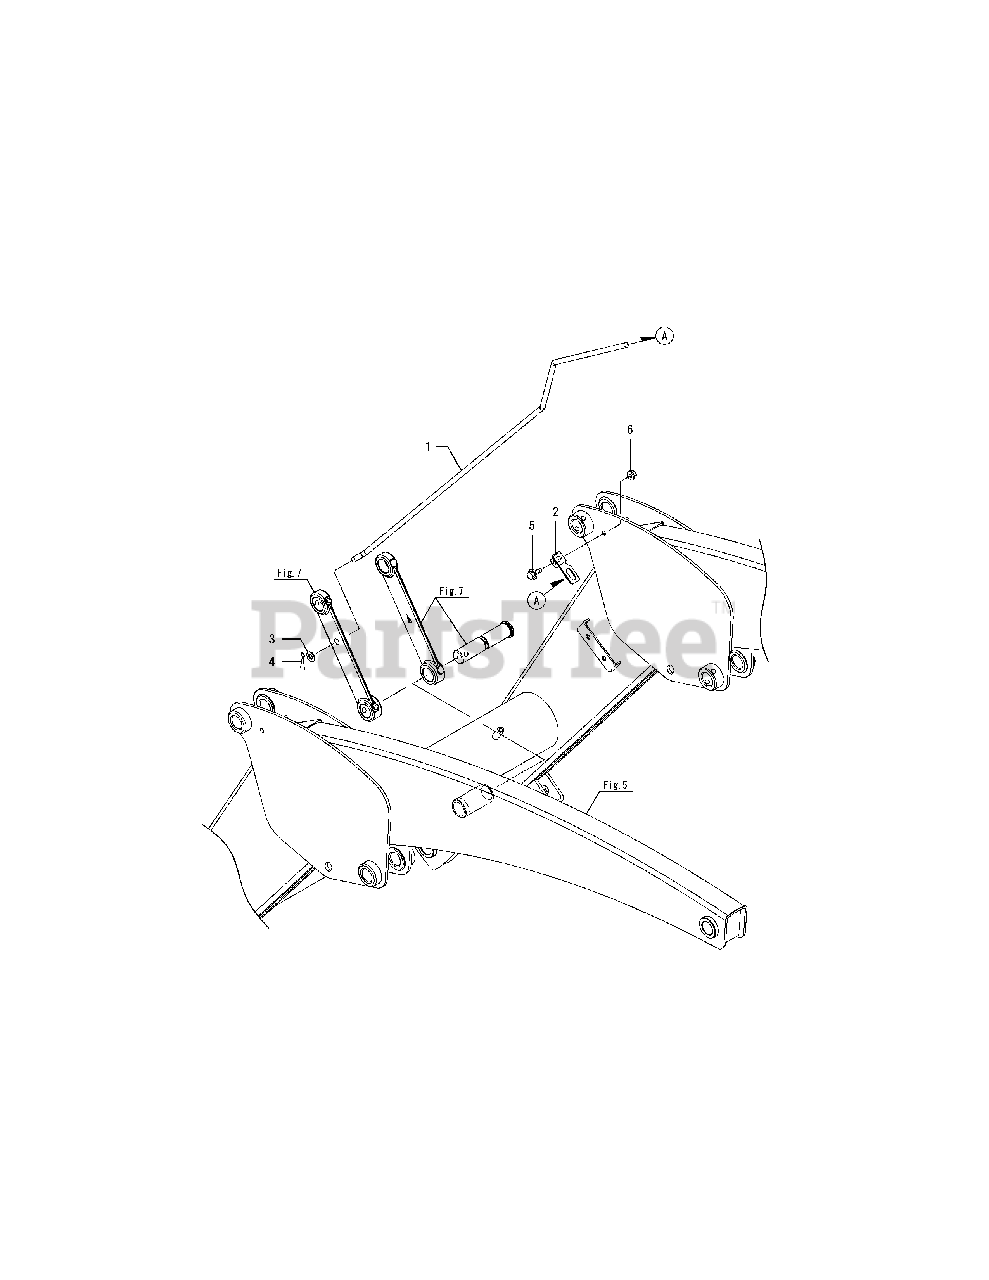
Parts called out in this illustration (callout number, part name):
1	LEVEL INDICATOR
2	STAY, INDICATOR
3	WASHER 10,POLISHED
4	COTTER PIN 2.5X30
5	BOLT M 8X 16 PLATED
